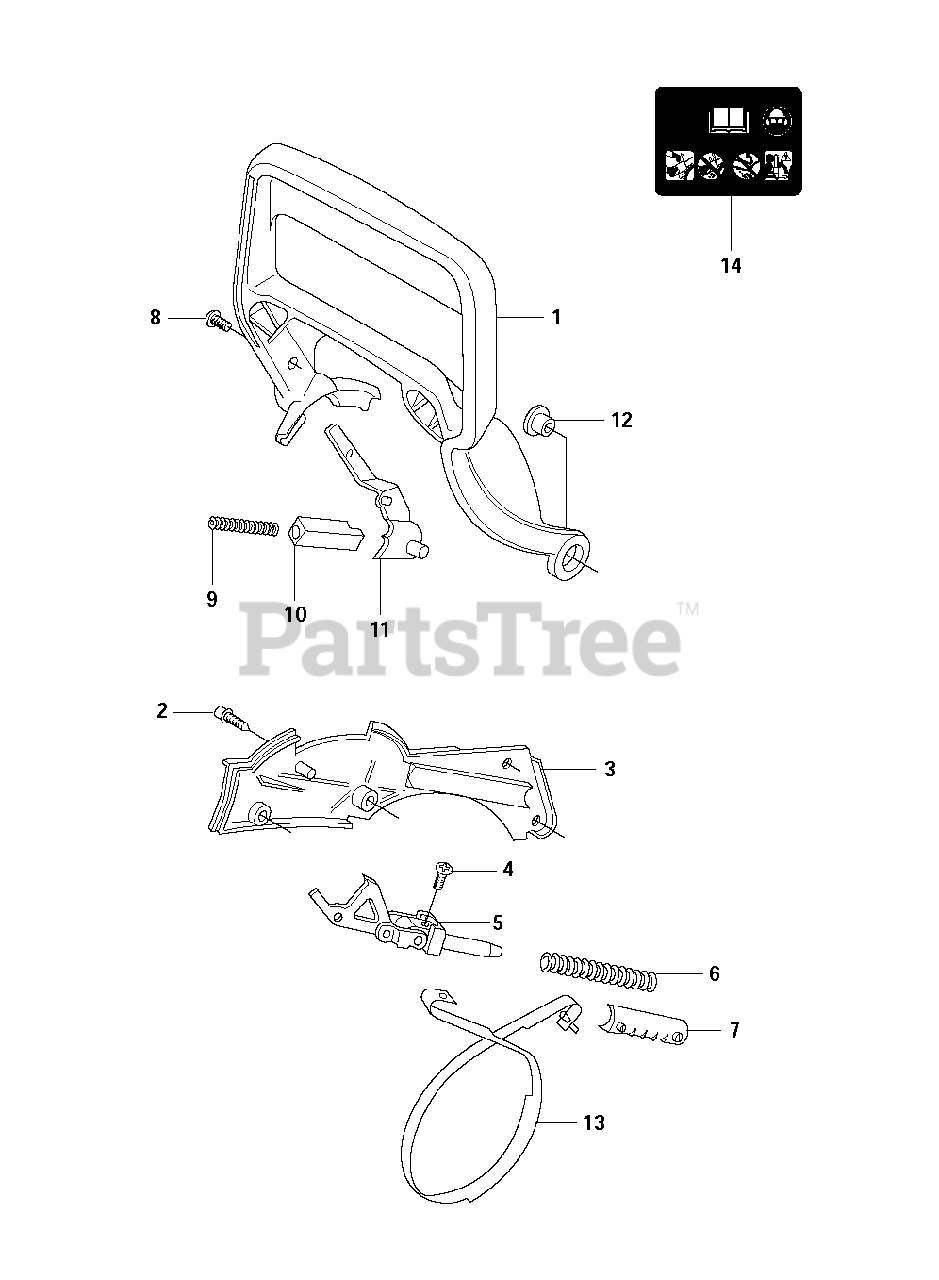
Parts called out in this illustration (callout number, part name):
1	HAND GUARD
5	KNEE LINK
6	BRAKE SPRING
9	LOCK SPRING
11	BRAKE LEVER
13	BRAKE BAND
14	DECAL
